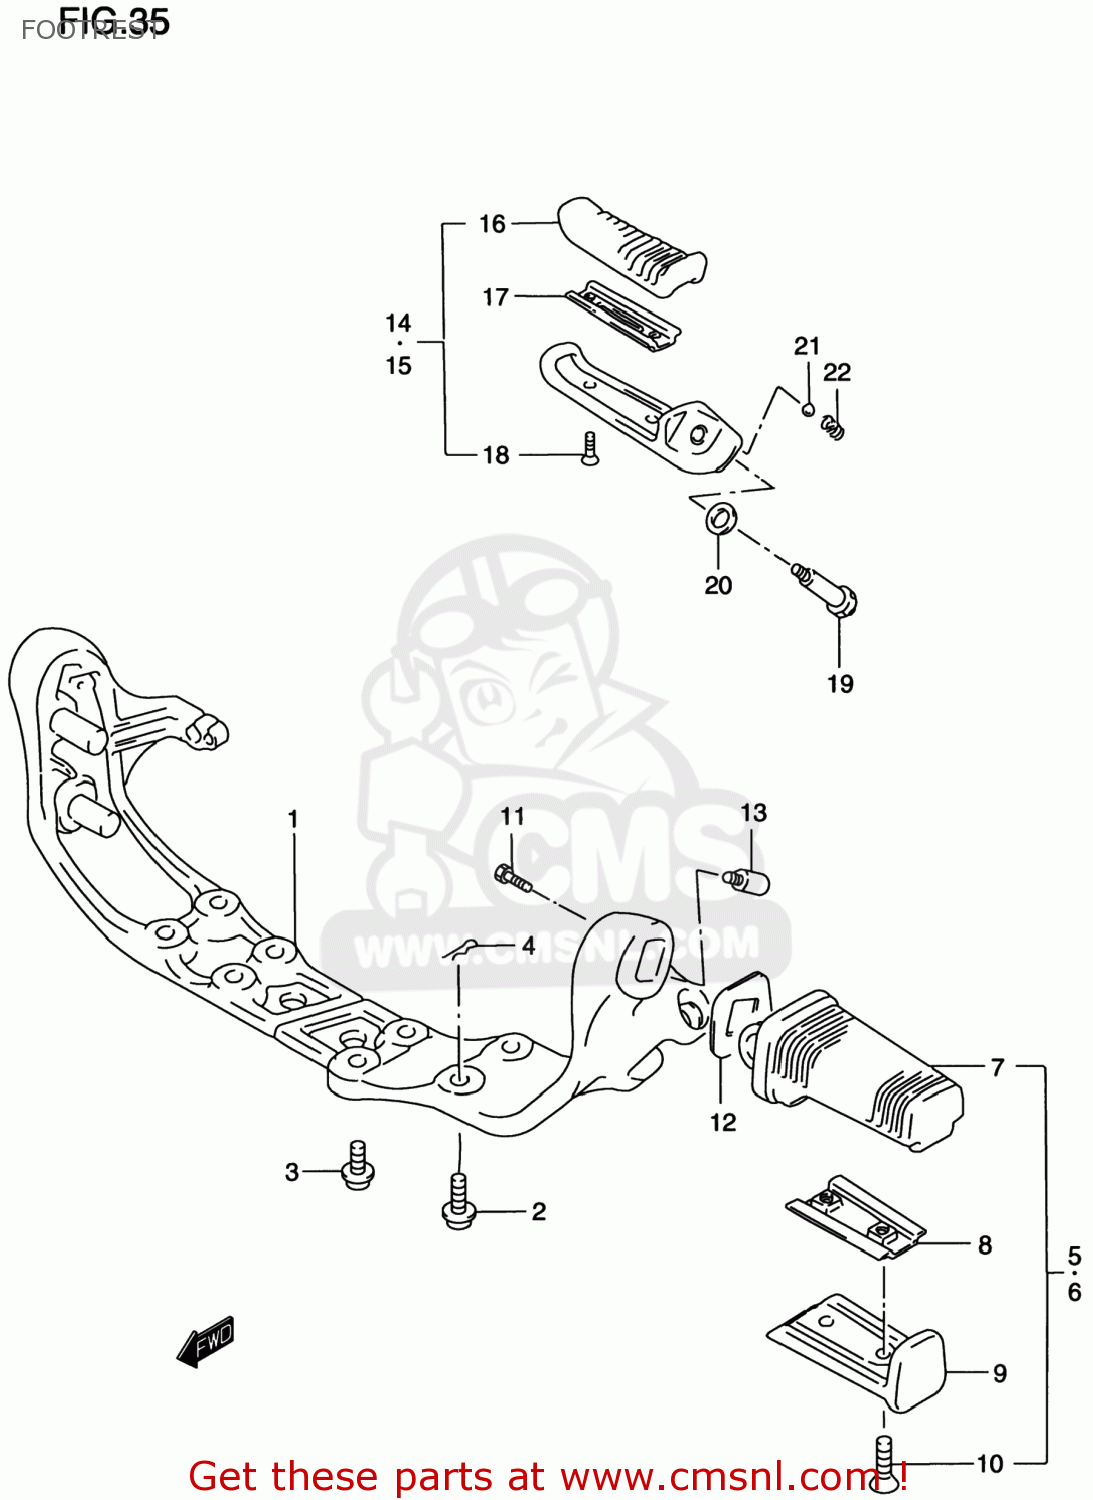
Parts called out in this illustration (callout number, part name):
1	BRACKET,FR FOOTREST
2	BOLT(8X25)
3	BOLT
4	SNAP
5	FOOTREST ASSY,FR,R
6	FOOTREST ASSY,FR,L
7	RUBBER,FR FOOTREST
8	PLATE,RUBBER STOPPER
9	COVER,FR FOOTREST
10	SCREW(5X20)
11	SCREW
12	WASHER,FR FOOTREST
13	BOLT,FRONT FOOTREST
14	FOOTREST ASSY RH
15	FOOTREST ASSY,PILLION,L
16	RUBBER,PILLION FOOTREST
17	PLATE,RUBBER STOPPER
18	SCREW(5X16)
19	BOLT(6X34.5)
20	SHIM
21	BALL
22	SPRING
